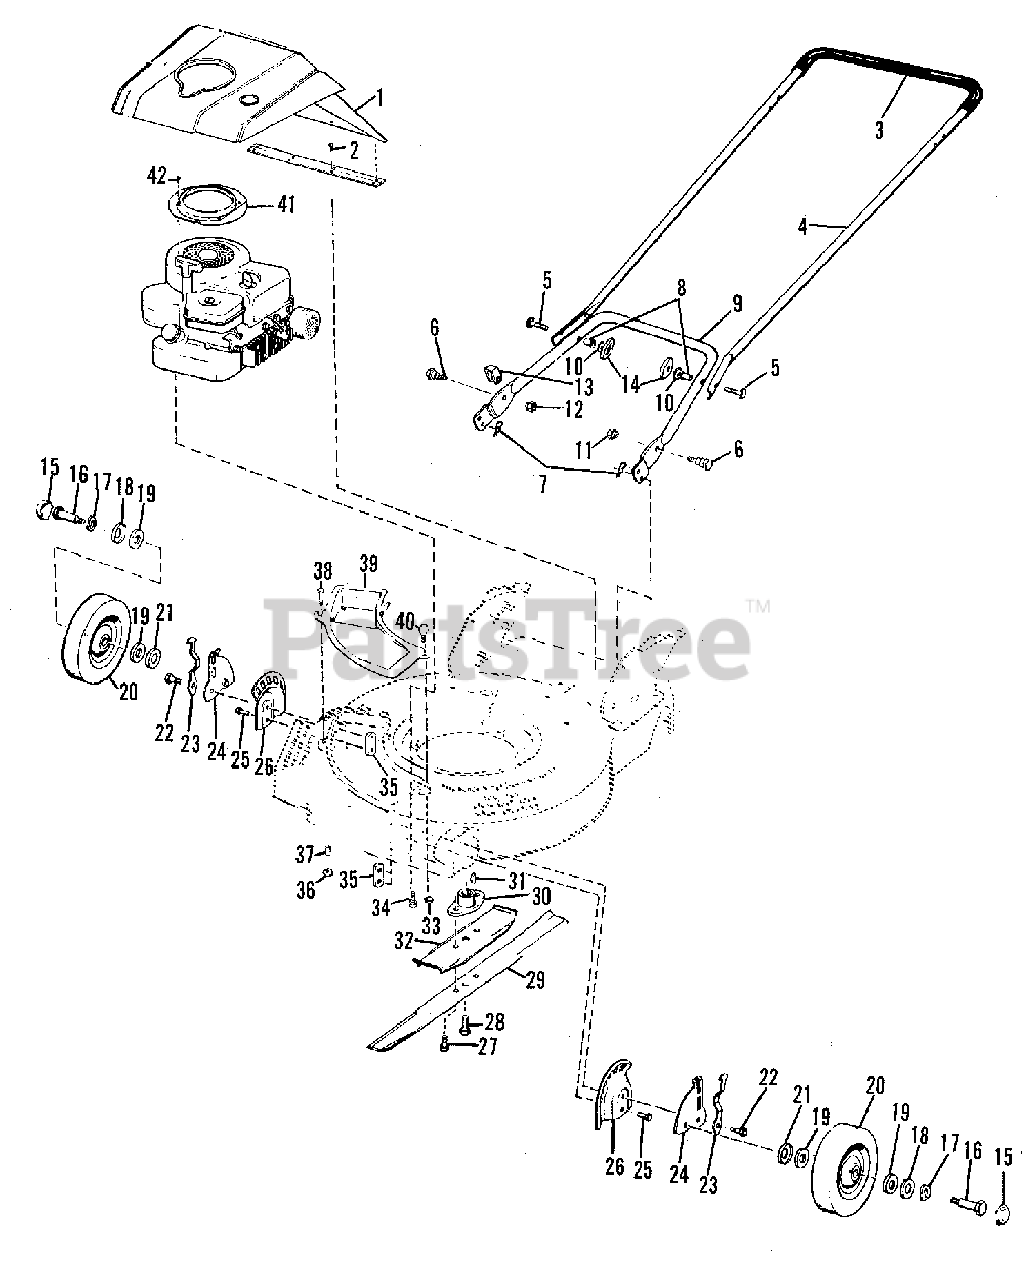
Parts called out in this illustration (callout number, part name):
2	SCREW, Hex, 12-24 x 1/2
3	TUBING, Handle
4	HANDLE, Upper
5	BOLT, Curved Head
6	BOLT, Handle Latch
7	CLIP, Spring
8	EYELET, Handle
9	HANDLE, Lower
10	WASHER, Flat, 1/4
11	NUT, Hex, 5/16-18
12	NUT, Handle Latch
13	LATCH, Handle
16	BOLT, Wheel (Front)
17	WASHER, Spring
18	HOUSING, Seal
20	WHEEL, 6" (Front)
21	HOUSING, Seal
22	BOLT, Hex, Shoulder
23	SPRING, Height Adjust (Front)
24	ADJUSTER, Height (Front)
25	SCREW, Hex, Cap, 3/8-16 x 5/8
26	PLATE, Adjusting
27	SCREW, Hex, 5/16-18 x 1
28	SCREW, Hex Cap, 3/8-24 x 1-1/2
30	ADAPTER, Blade
31	KEY, Woodruff, #6
32	STIFFENER, Blade
33	SPEED NUT, Special
34	SCREW, Engine Mounting, 3/8-16 x 1
35	NUT, Twin Pilot
36	NUT, Hex, 1/4-20
38	SCREW, Special
39	PLATE, Cover
40	SCREW, Thumb, 1/4-20 x 5/8
